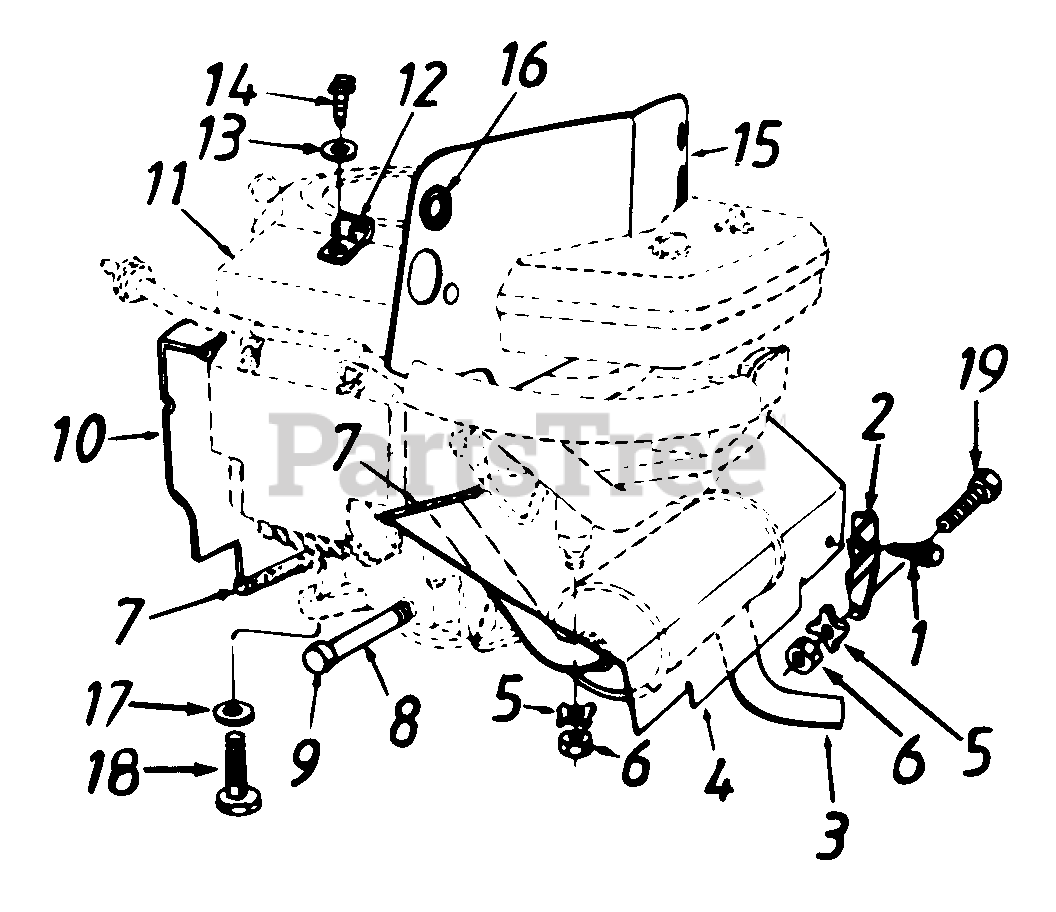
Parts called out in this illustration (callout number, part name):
1	Hex AB-Tap Scr. 1/4 x .62"
3	Muffler
4	Front Heat Shield
5	Spec. L-Wash. 5/16 x .88"
6	Hex Nut 5/16-18 Thd.
7	Trim Strip 12" Lg.
8	Pipe Nipple
9	Oil Drain Cap
10	Rear Baffle
11	Engine
12	Clamp
13	Fl-Wash .188" I.D. x .438"
14	Truss Mach. AB-Tap Scr. #10 x .5" Lg.
15	Heat Shield
16	Rubber Grommet
17	Fl-Wash .406" I.D. x 1-1/4" O.D.
18	Hex L-Wash. TT-Tap Scr. 3/8-16 x 1.5" Lg.
19	Hex Bolt 5/16-18 x 5/8" Lg.
